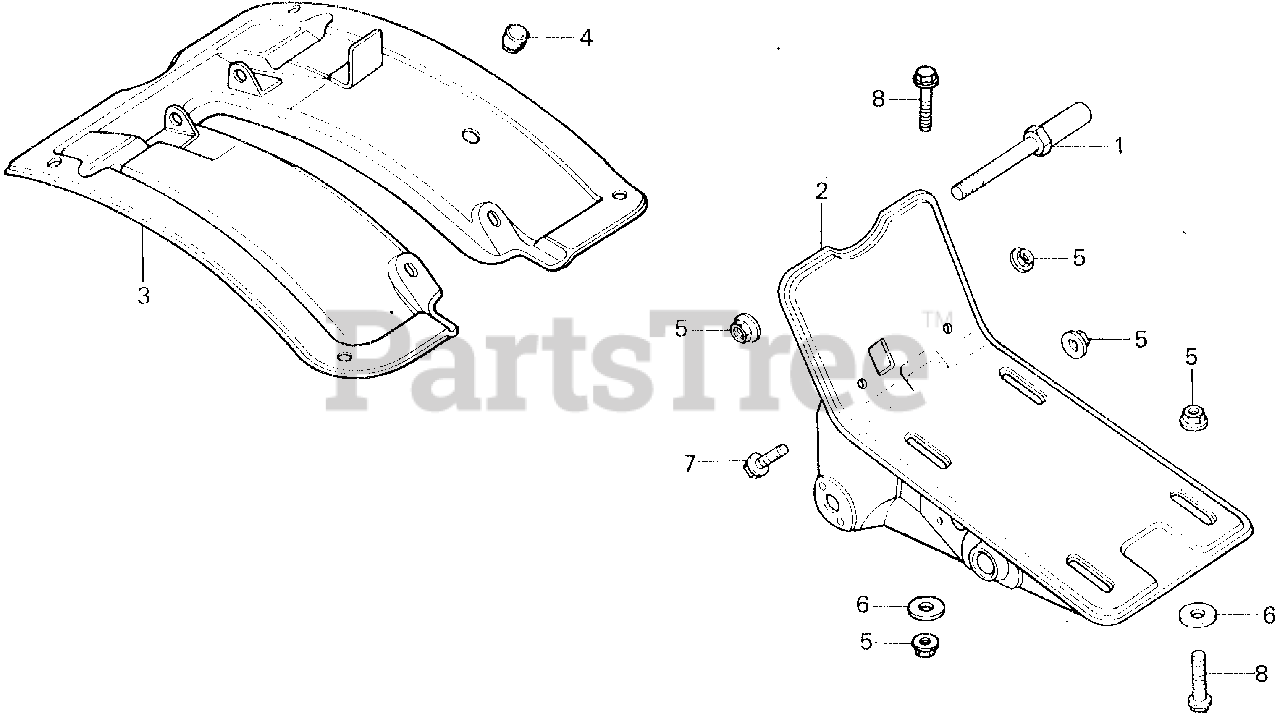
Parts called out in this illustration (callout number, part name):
1	BOLT, TENSIONER ARM
2	BED, ENGINE
2	BED, ENGINE (NOT AVAILABLE)
3	FENDER, MAIN *NH31* (MCKINLEY WHITE)
4	STOPPER, TENSIONER ARM
5	NUT, FLANGE (8MM)
6	WASHER (8X22)
7	BOLT, FLANGE (8X16)
8	BOLT, FLANGE (8X40)
NI	BOLT, FLANGE (8X45)
